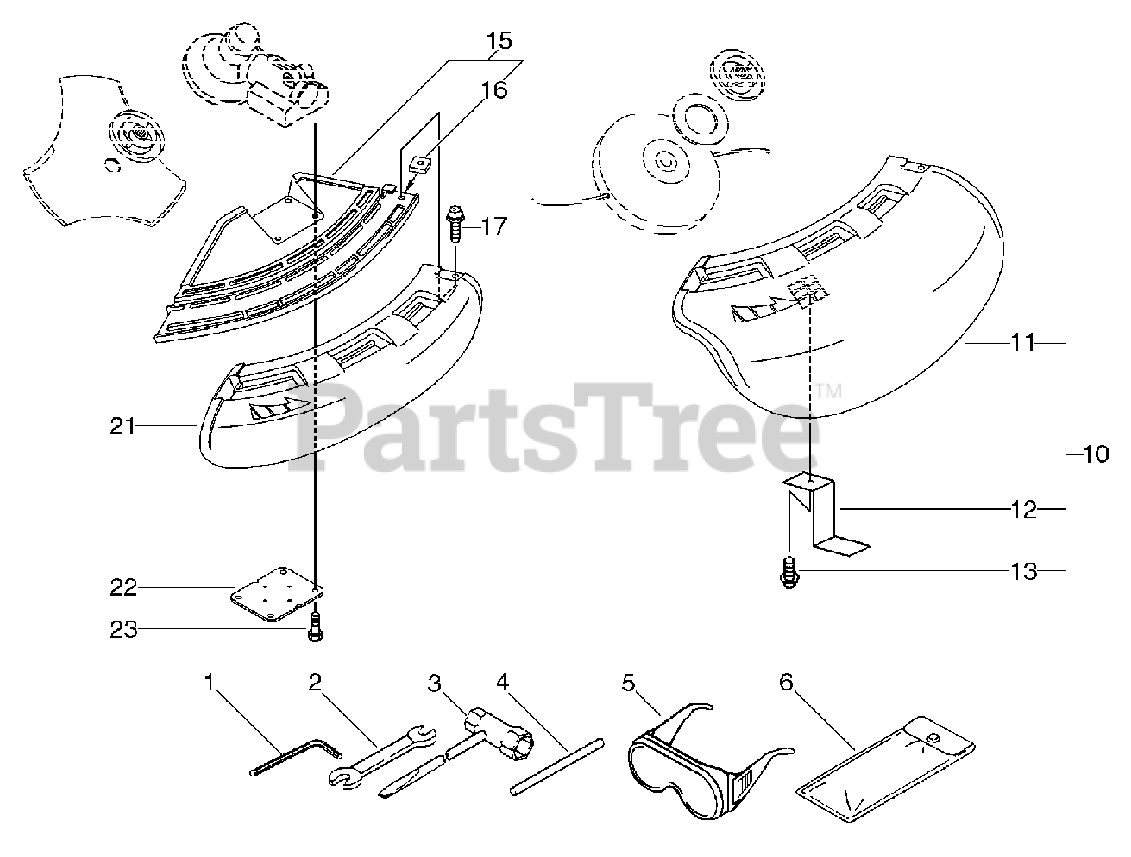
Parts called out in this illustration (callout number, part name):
1	HEX KEY - 4mm
2	SPANNER - 8X10mm
3	T-WRENCH - 17X19mm
4	LOCKING TOOL
5	GOGGLES
6	BAG, TOOL
10	DEBRIS SHIELD KIT - TRIMMER
11	SHIELD, DEBRIS - TRIMMER
12	KNIFE, TRIMMER LINE
13	SCREW - 5X12
16	NUT
17	SCREW - 5X18
20	ADAPTOR, DEBRIS SHIELD
21	SHIELD, DEBRIS - BLADE
22	BRACKET, SHIELD
23	SCREW - 5X25
